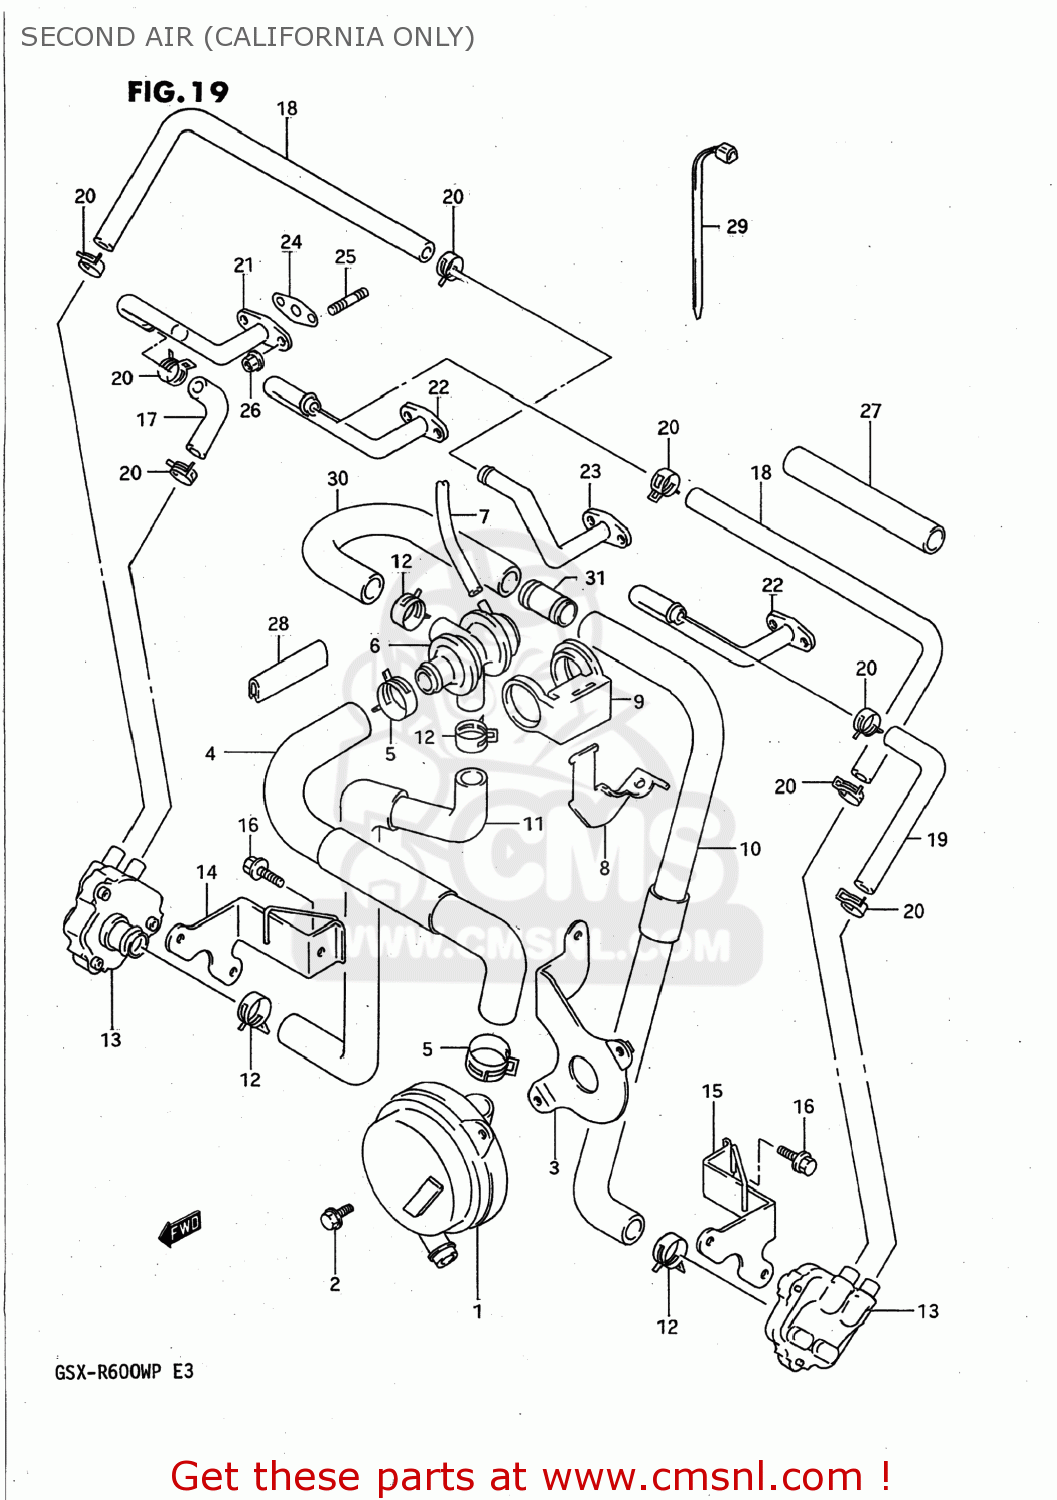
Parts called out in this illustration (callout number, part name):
1	CLEANER ASSEMBLY,SECOND AIR
2	BOLT 6X12
3	BRACKET,SECOND CLEANER
4	HOSE,SECOND AIR CLEANER
5	CLAMP
6	VALVE ASSY,2ND AIR SWITCHING
7	HOSE
8	BRACKET,SECOND AIR VALVE
9	CUSHION,2ND AIR VALVE
10	HOSE,SECOND AIR VALVE NO
11	HOSE,SECOND AIR VALVE NO
12	CLIP
13	VALVE ASSY,2ND AIR REED
14	BRACKET,REED VALVE,RIGHT
15	BRACKET COMP,REED VALVE
16	BOLT
17	HOSE,SECOND AIR REED VALVE
18	HOSE,SECOND AIR REED VALVE
19	HOSE,SECOND AIR REED VALVE
20	CLIP
21	PIPE,SECOND AIR NO.4
22	PIPE,SECOND AIR NO.1
23	PIPE,SECOND AIR NO.2
24	GASKET,SECOND AIR PIPE (N (NAS)
25	STUD BOLT
26	NUT 6MM
27	TUBE, INTERFERENCE HOSE
28	MOLDING,FUEL TANK RR
29	CLAMP(L:165)
30	HOSE,SECOND AIR VALVE NO
31	UNION,SECOND AIR VALVE HOSE
